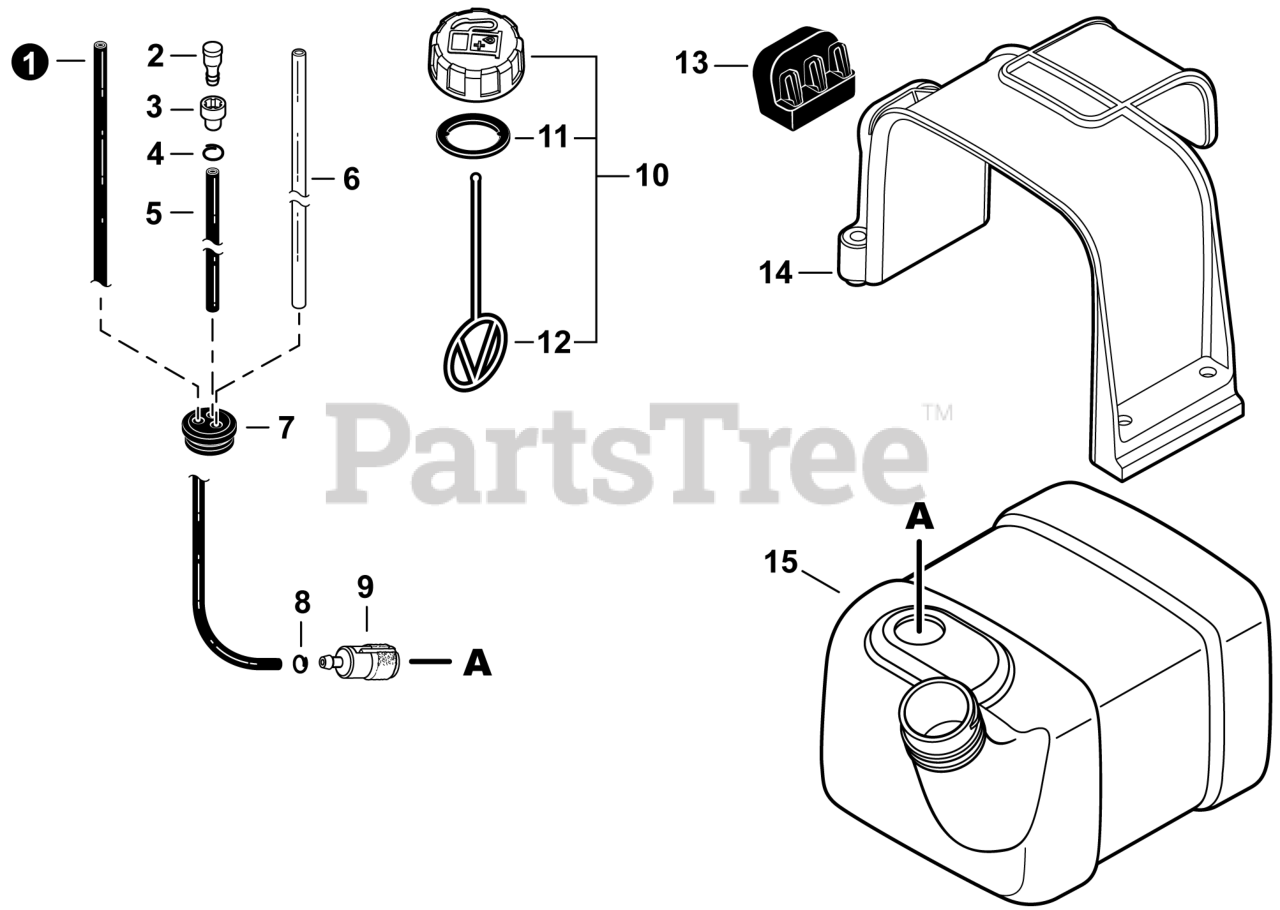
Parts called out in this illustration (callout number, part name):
1	PIPE, FUEL 3x5x325 BLACK
2	VENT ASSY
3	HOLDER, VENT
4	CLIP 6.5 MM
5	PIPE, FUEL 3x6x40 BLACK
6	PIPE, FUEL 3x6x180 YELLOW
7	GROMMET, FUEL
9	FILTER, FUEL
10	CAP ASSY, FUEL
11	GASKET, FUEL CAP
12	CONNECTOR, CAP L= 100 MM
13	CUSHION
14	RETAINER, FUEL TANK
15	TANK, FUEL
